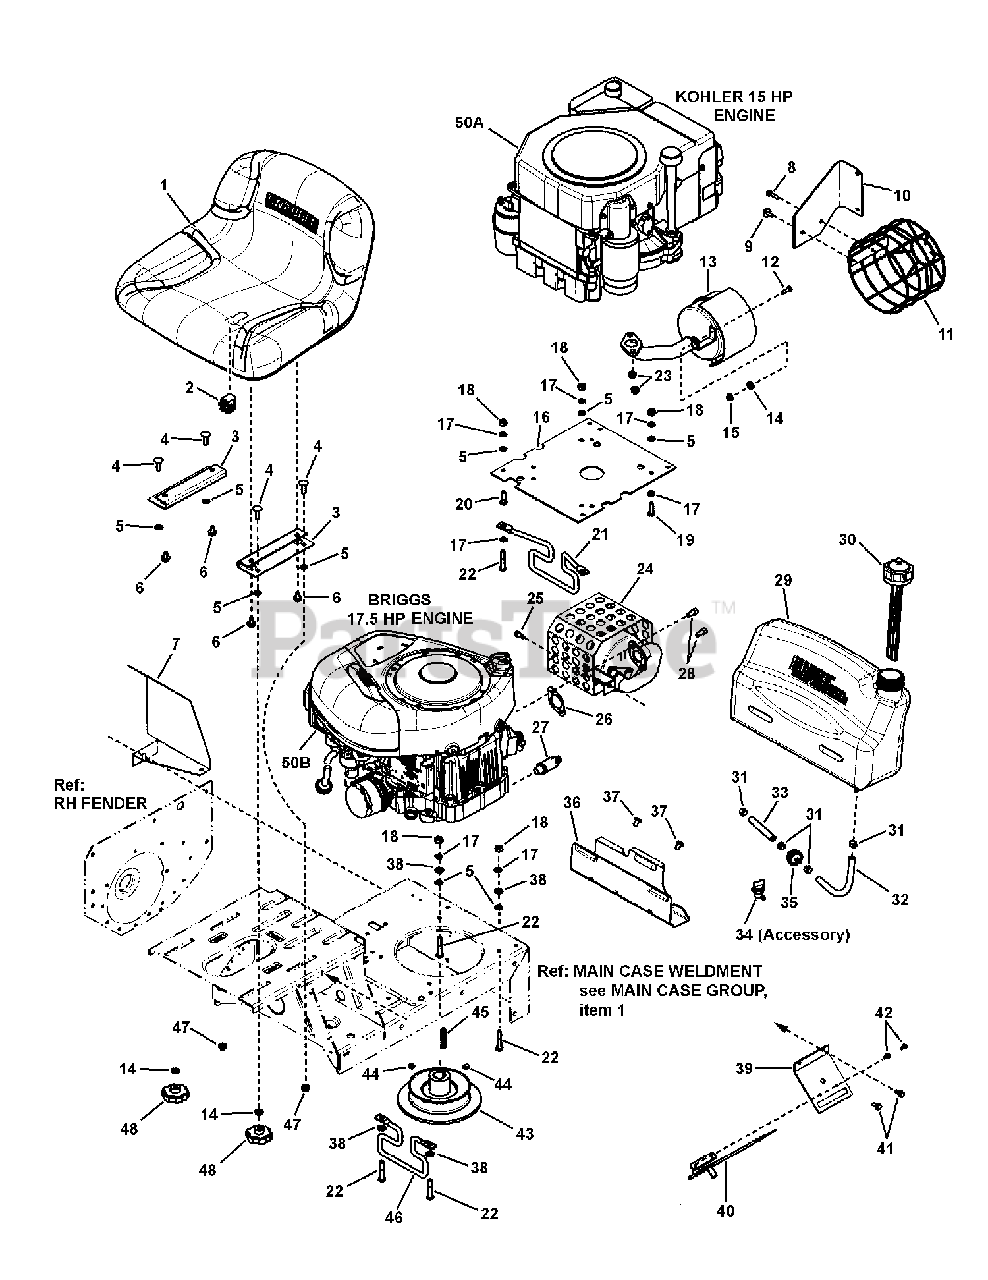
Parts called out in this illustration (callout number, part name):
1	SEAT, Operator (11.58" tall) (Michigan V-2400 Series)
2	SWITCH, Seat (NC)(Gray)
3	BRACKET, Seat
4	BOLT, 5/16-18 x 1" Square Neck Carriage, GR 5 YZ
5	RETAINER, 5/16" Bolt
6	BOLT, 5/16-18 x 1/2" Hex Flange Nyloc
7	GUARD, Manifold, RER
8	SCREW, 1/4-20 x 1" Hex Head Cap, GR 5
9	SCREW, 1/4-20 x 5/8" Hex Head w/Free Spinning Washer
10	BRACKET, Muffler Guard (Kohler)
11	MUFFLER GUARD, Kohler
12	SCREW, 1/4-20 x 3/4" Hex Head Cap, GR 5
13	MUFFLER, (Kohler 14 & 15HP)
14	SPACER, .33 x .63 x .156
15	NUT, 1/4-20 Hex Flange Lock
16	PLATE, Engine (Kohler Engine)
17	WASHER, .32 x .58 x .08 Split Lock
18	NUT, 5/16-24 Hex, GR 5
19	BOLT, M8-1.25 x 25mm, Self-Tap (Kohler)
20	SCREW, 5/16-24 x 1" Hex Head Cap, GR 5
21	BELT GUIDE, K 30/33"
22	SCREW, 5/16-24 x 1-3/4" Hex Head Cap, GR 5
23	NUT, 5/16-18 Hex Flange Lock, GR 5
24	MUFFLER w/Guard (Briggs 17.5HP)
25	SCREW, 1/4-20 x 5/8" Hex Washer Head Self-Tap
26	GASKET, Exhaust
27	ASSEMBLY, Oil Valve
28	SET SCREW, 5/16-18 x 3/4" Socket Head, GR8
29	ASSEMBLY, Fuel Tank with Gauge (Includes Cap)
30	CAP, Fuel Tank w/Gage
31	CLAMP, Fuel Line (.490 X .31)
32	HOSE, Fuel (1/4" I.D. x 8-1/2" long)
32	HOSE, Fuel (1/4" I.D. x 12-1/2" long)
32	HOSE, Fuel (1/4" I.D. x 6-1/2" long)
33	HOSE, Fuel (1/4" I.D. x 3-1/2" long)
34	VALVE, Fuel Shut-Off (Accessory)
35	FILTER, Fuel (In-Line)
36	BRACKET, Fuel Tank (Rear)
37	SCREW, 5/16-18 x 1/2" Pan Head Self-Tap (Torx #T-40)
38	WASHER, 11/32" Flat
39	PLATE, Throttle Control
40	CONTROL, Throttle (23.6" long) (Briggs Engines)
40	CONTROL, Throttle (34.6" long) (Kohler Engines)
41	SCREW, 1/4-20 x 1/2" Hex Washer Self-Tap
42	SCREW, #10-24 x 1/2" Hex Washer Self-Tap (Torx)
43	WELDMENT, 5.25" O.D. Drive Disc
44	SET SCREW, HRSS, 3/8-16 x 3/8"
45	KEY, 1/4" Square x 2" Long
46	BELT GUIDE, 30/33"
47	NUT, 5/16-18 Hex Flange Top Lock
48	KNOB, Fluted, 5/16-18 internal thread (2.15 O.D.)
50A	* ENGINE, 15 HP Kohler
50B	* ENGINE, 17.5 HP Briggs Intek w/AVS Euro
